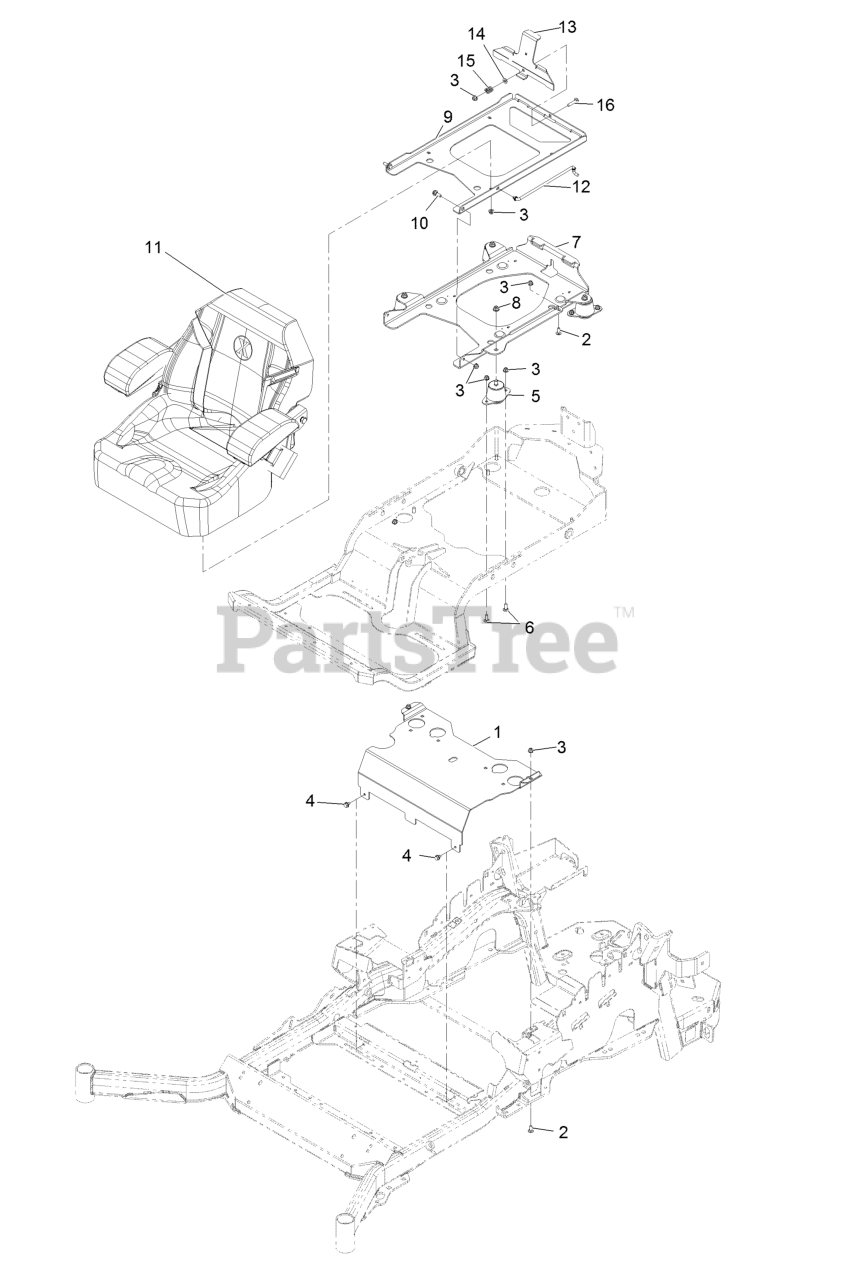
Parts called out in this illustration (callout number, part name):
1	Panel-Front, Seat Mount
2	Bolt-Carriage 5/16-18 X 3/4 Short Neck
3	Nut-Nyloc 5/16-18 Flg
4	Screw-HWH 5/16 X 1/2 Tf
5	Isolator-Seat
6	Bolt-Carriage 5/16-18 X 7/8
7	Plate-Support, ISO Seat
8	Nut-Nyloc 3/8-16 Flg
9	Plate-Frame, Seat
10	Screw-Shoulder
11	Seat-Exmark Standard
12	Rod-Prop
13	Plate-Latch,Seat
14	Washer-5/16 SAE
15	Spring-Compression
16	Bolt-Carriage 5/16-18 X 1 1/2
